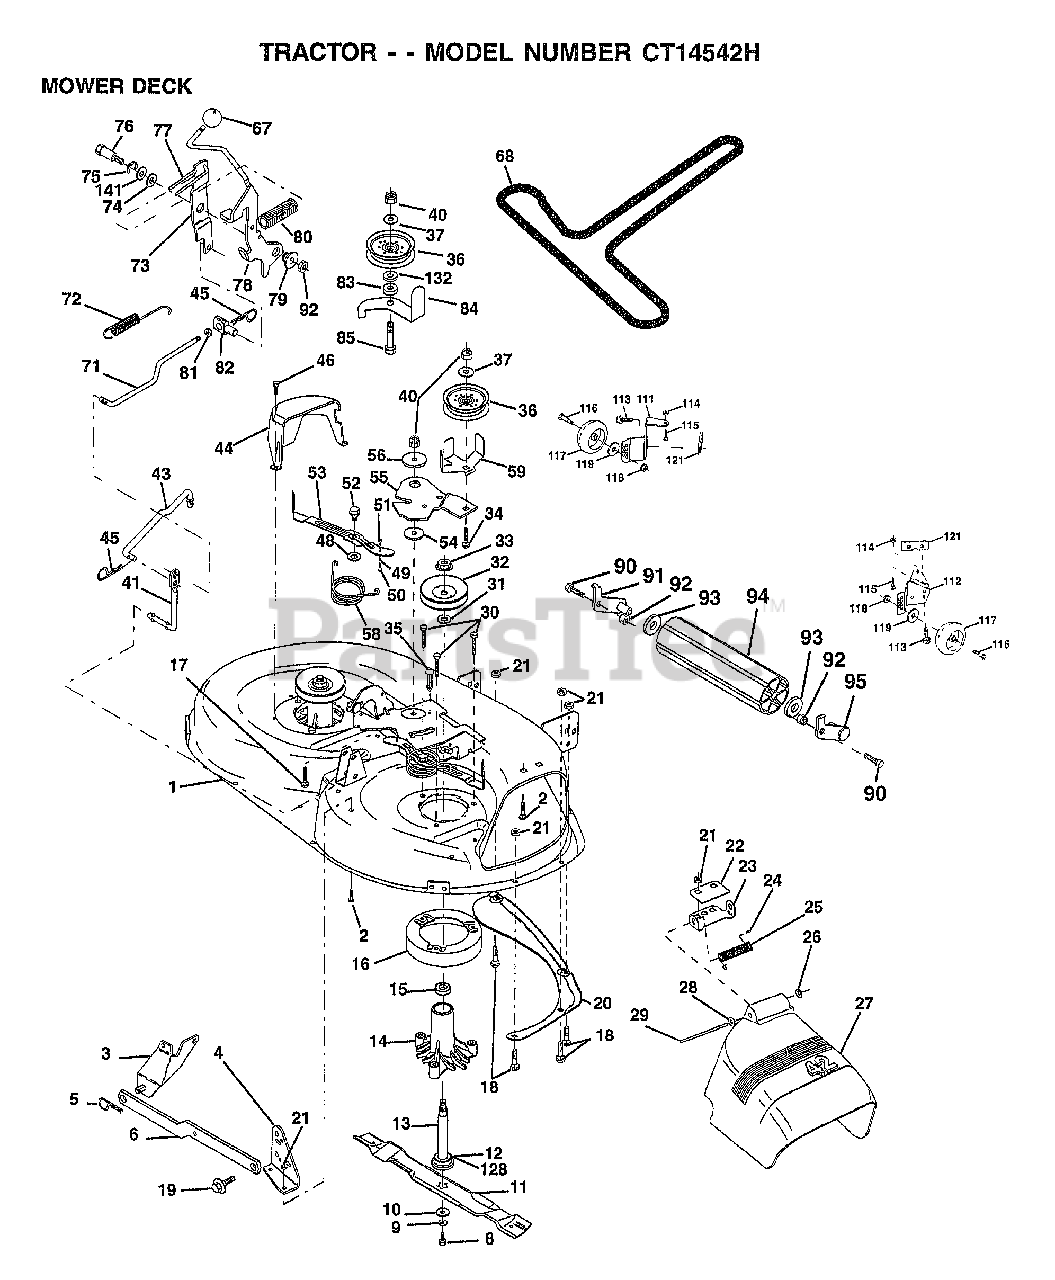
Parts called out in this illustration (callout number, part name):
1	"HOUSING ASSY.42"""
2	BOLT
3	BRKT ASM SWAY BAR
4	BRKT DECK SW BAR
8	BLADE BOLT
10	WASHER.HARD.BLADE
11	"BLADE.42"" HIPERF"
12	BEARING.BALL
14	HSG ASM MANDREL
15	BEARING
16	STRIPPER RND MWR
17	BOLT RDHD 3/8-16
18	BOLT
19	BOLT SHD 5/16-18
20	BAFFLE VORTEX 42
22	STIFFENER BRKT
23	DEFLECTOR BRKT
24	CAP-SLEEVE LT
25	SPRING TORSION
26	NUT PUSH M
27	DEFLECTOR.SHIELD
28	WASHER
29	HINGE ROD
30	"SCREW-THD ROLL,WA"
31	WASHER
32	PULLEY.MANDREL.42
34	BOLT
35	XMAS TREE FASTNER
36	FLAT IDLER PULLEY
37	WASHER
41	PIVOT ROD
43	ROD CLUTCH W/NIBS
44	GUARD MAND LH BLK
45	RETAINER M
46	SCREW.1/4-20X5/8
48	HARD SMALL WASHER
49	ROLLER ASM-CAM
50	SHOULDER BOLT
51	LOCKNUT
52	BOLT.SHLD.5/16-18
53	BRAKE PAD ARM ASM
54	HARDENED WASHER
55	ARM-IDLER
56	SPACER RETAINER
58	SPRING TORSN BRAK
59	GUARD IDLER TUV
67	KNOB.RD.7/16-14
68	BELT.V.T-PATH
71	ROD CLUTCH 38/42
72	RETURN SPRING
73	CLUTCH ARM SECOND
74	WASHER
75	RING
76	SHOULDER BOLT
77	SPRING KEEPER
78	LEVER.ASM.CLUTCH
79	BUSHING
80	SPRING.CLUTCH.MWR
81	NUT
82	TRUNION ADJ
83	WASHER
84	"KEEPER-BELT,FIXED"
85	BOLT
90	BOLT
92	NUT
93	WASHER
111	BRACKET.GWHL.LH.
112	BRACKET.GWHL.RH.
113	SCREW
116	BOLT M
117	WHEEL.GUAGE
118	LOCKNUT
119	WASHER
121	BRACKET.EXTRD.GWL
128	WASHER.FELT.
132	WASHER GT
141	WASHER .T
